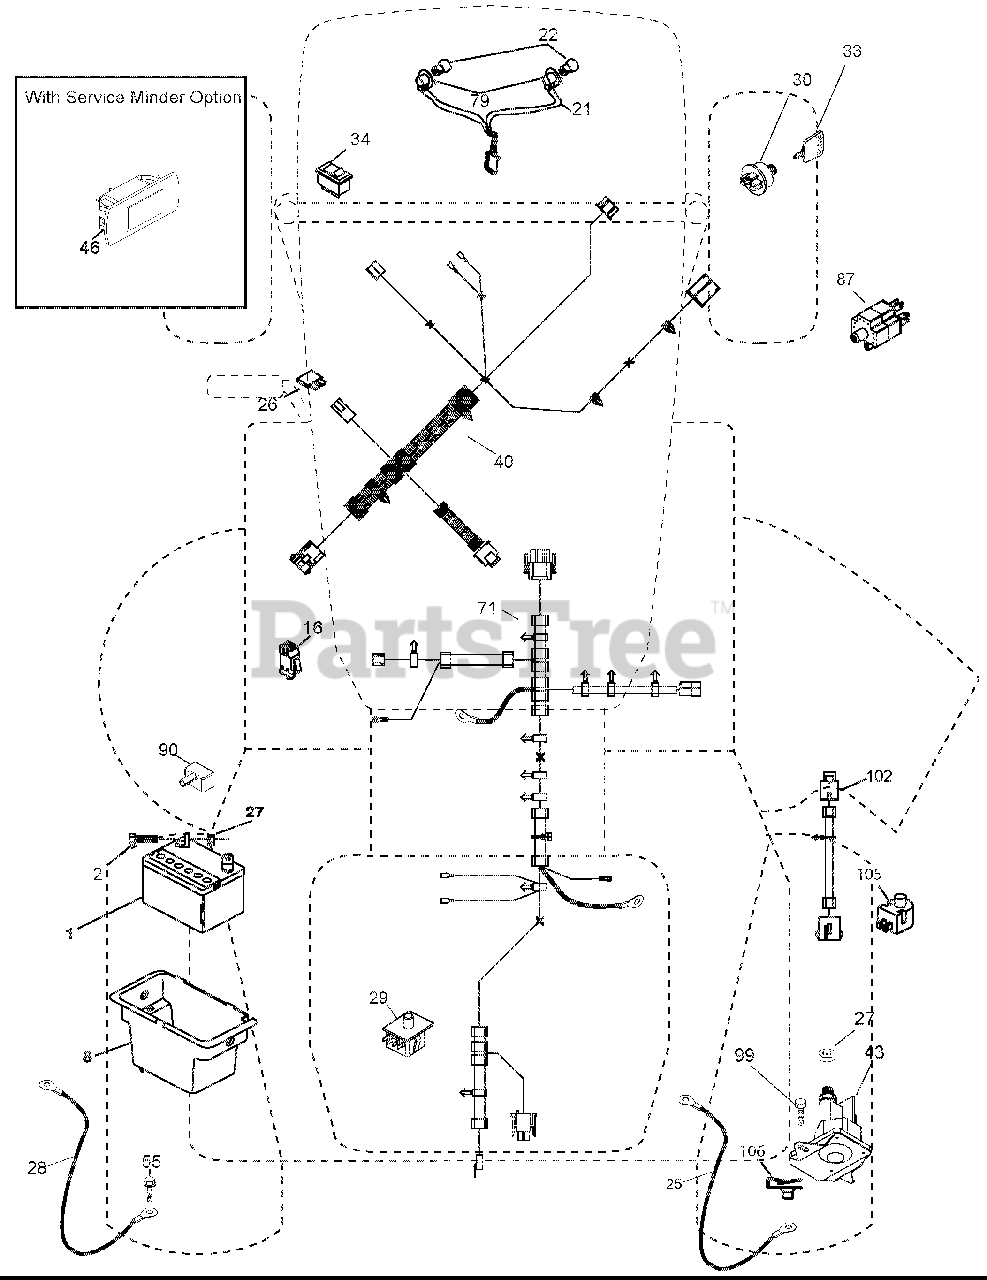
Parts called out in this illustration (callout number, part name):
1	BATTERY.12.VOLT.28.AMP.WET
2	BOLT.HEX.HD.1/4-20UNC X 3/4
8	BOX.BATTERY.MNT.REAR.LT.TEX.BL
16	SWITCH.INTERLOCK.NONO.GRAY
21	HARNESS ASM.LIGHT.22"(4152J)
22	BULB.LIGHT.#1156
25	CABLE STARTER 6 G4. BL/RED14.5
26	FUSE.20 AMP.
27	Nut, Keps Hex 1/4-20 unc
28	CABLE.BLACK.22"REAR BATT.TEX
29	SWITCH.SEAT.DELTA.OPC.9LB.
30	SWITCH.IGN.DLTA.P-IN.ROS
33	KEY/CHAIN.BLISTER PACK.GEN.USA
34	SWITCH.LIGHT/RESET.B/B/RED.
40	HARNESS.IGN.DASH.CBL.YTGT.PRED
43	SOLENOID.W/BRASS PLUNGER.2005
55	SCREW.5/16-18X3/4.SMGML.TAP/R
71	HARNESS.IGN.CHASSIS.TEX
79	SOCKET ASM.BULB.TWISTLOCK
87	SWITCH.INTRLCK.CLUTCH.CABLE.TX
90	COVER TERMINAL BATTERY FR. TEX
102	HARNESS.PIGTAIL
105	SWITCH.REVERSE.TT.PEDAL CONTRO
